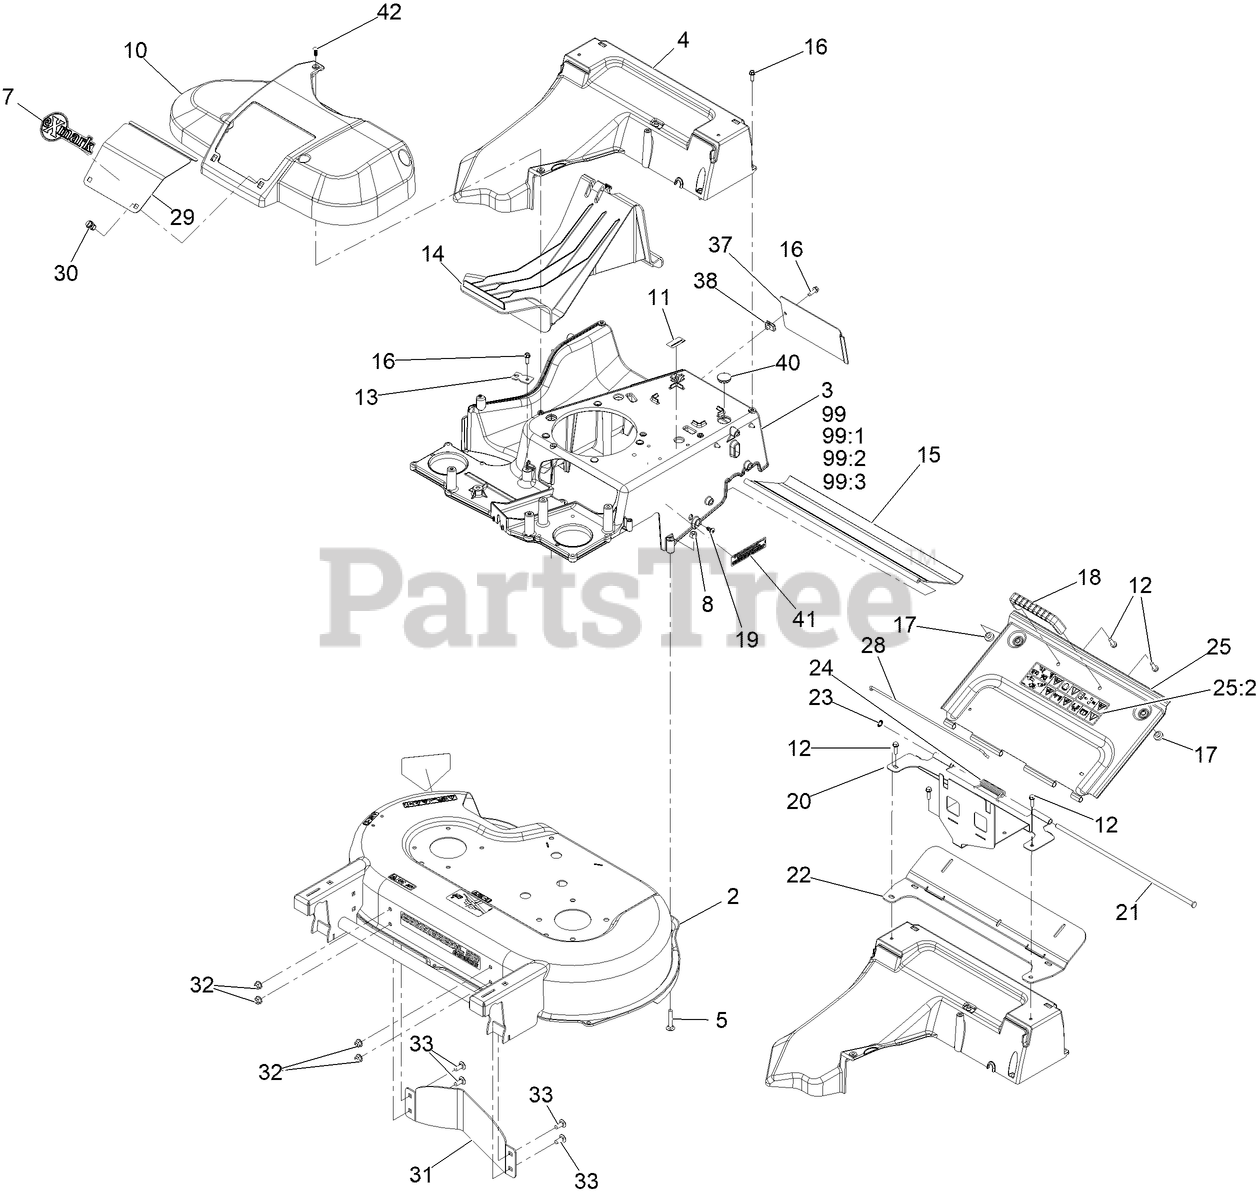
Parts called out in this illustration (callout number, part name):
2	DECK-30, X-SERIES W/DECALS
5	BOLT-CAR
7	DECAL-EXMARK LOGO
8	NUT-LOCK, NI
10	COVER-BELT
11	Decal-Patent Ttco.Com
12	SCREW-HWH
13	BRACKET-CABLE, TRACTION
14	PLUG-MULCH
15	SHIELD-TRAILING
16	SCREW-HWHTF
18	HANDLE-DOOR
19	SCREW-PTH
20	Weld-Tank Mount
21	PIN-HINGE
22	SEAL-DOOR
23	RING-RETAINING
24	SPRING-TORSION, COVER
25	REAR DOOR ASM
25:2	DECAL-WARNING
28	CLIP-SEAL
29	DOOR-ACCESS
30	FASTENER
31	BAFFLE-CONTROL
32	NUT-HF, NI
33	SCREW-HSBH
37	Cover-Frame
40	PLUG-BUTTON
41	DECAL-ARRESTOR, SPARK
42	Clip-Xmas Tree
99	FRAME PLATE KIT
99:1	PLATE-FRAME
99:2	SCREW-CARR
99:3	NUT-LOCK, NI
